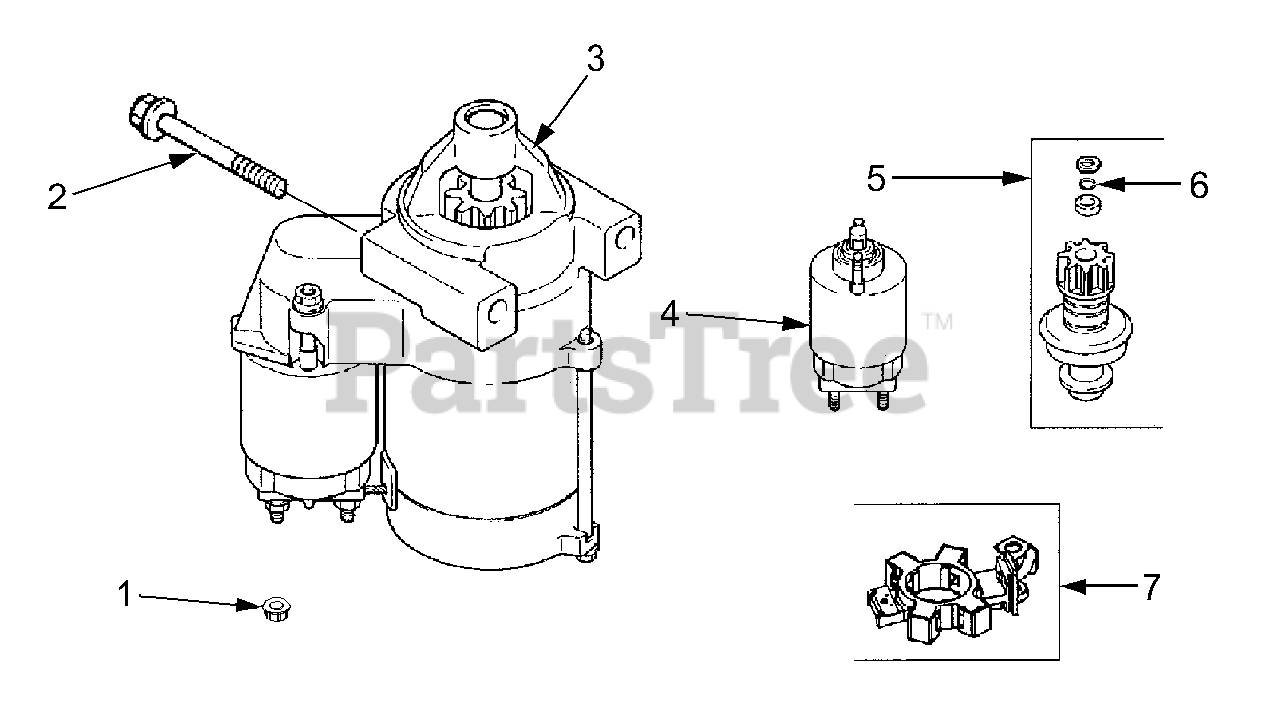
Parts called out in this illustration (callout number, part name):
1	Nut, Hex Flange M8 x 1.25"
2	Screw, Hex Flange M8 x 1.25 x 80
3	Starter, Solenoid Shift Assembly
4	Kit, Solenoid
5	Kit, Pinion Drive
6	Ring, Retainer
